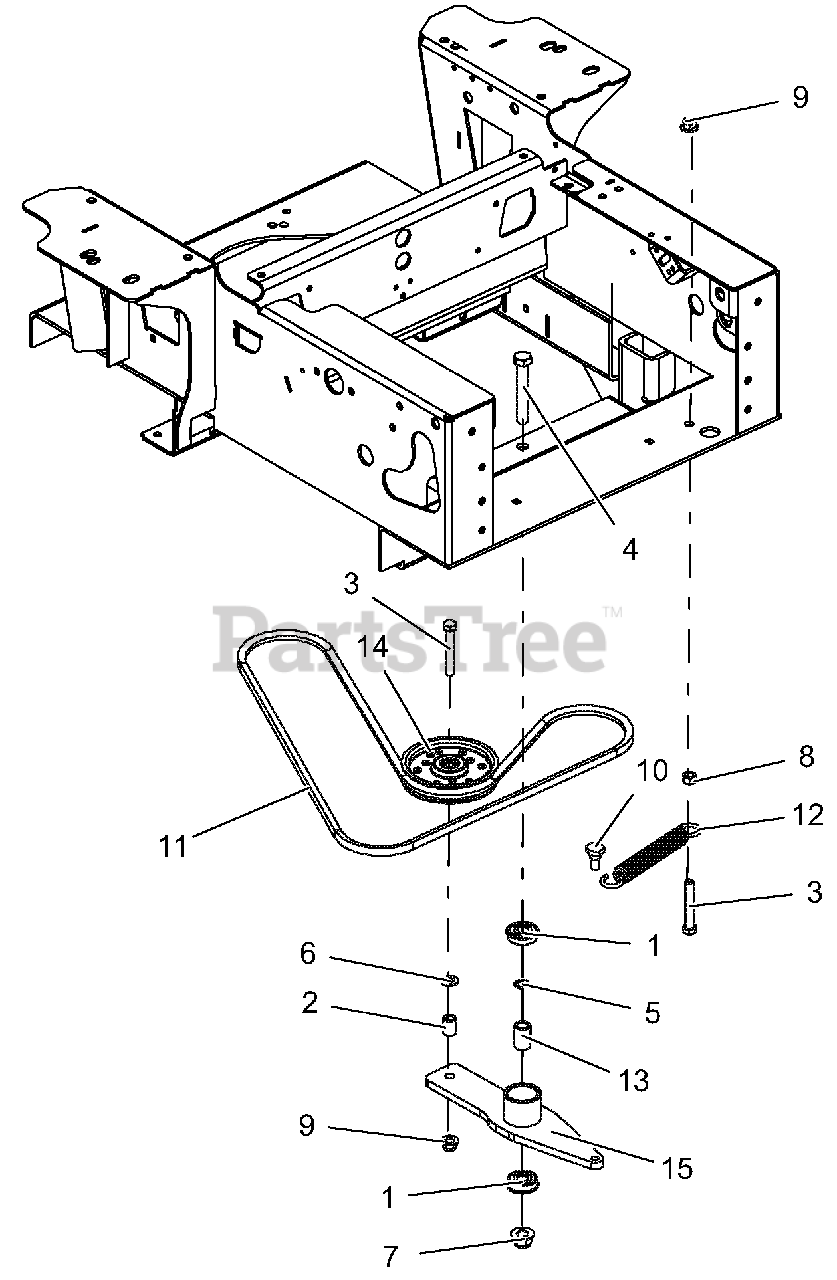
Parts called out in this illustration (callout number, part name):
1	BRG, BALL .501 X 1.38 X .438 SEALED
2	BSHG-SLV .407X.625X.750
3	BLT-HEX .38-16X2.50 GR5 YWZC
4	BLT-HEX .50-13X3.25 GR5 YWZC
5	WASHER-FLAT-STL, .500 X .750 X .020
6	WSHR-FL-STL.406X.812X.065 YWZ
7	NUT-LK-NYL-FLG .50-13 YWZC
8	NUT-HEX .38-16 YWZC
9	NUT-LK-NYL-FLG .38-16 YWZC
10	BLT, SHLDR EP .38-16X.30 HEX YZ
11	BELT, V-A-COGGED
12	SPRG, EXTENSION
13	SPACER, .510 X .750 X 1.148
14	ASM, IDLER 4"
15	WLDMT, HYDRO DRIVE IDLER ARM-BLACK
